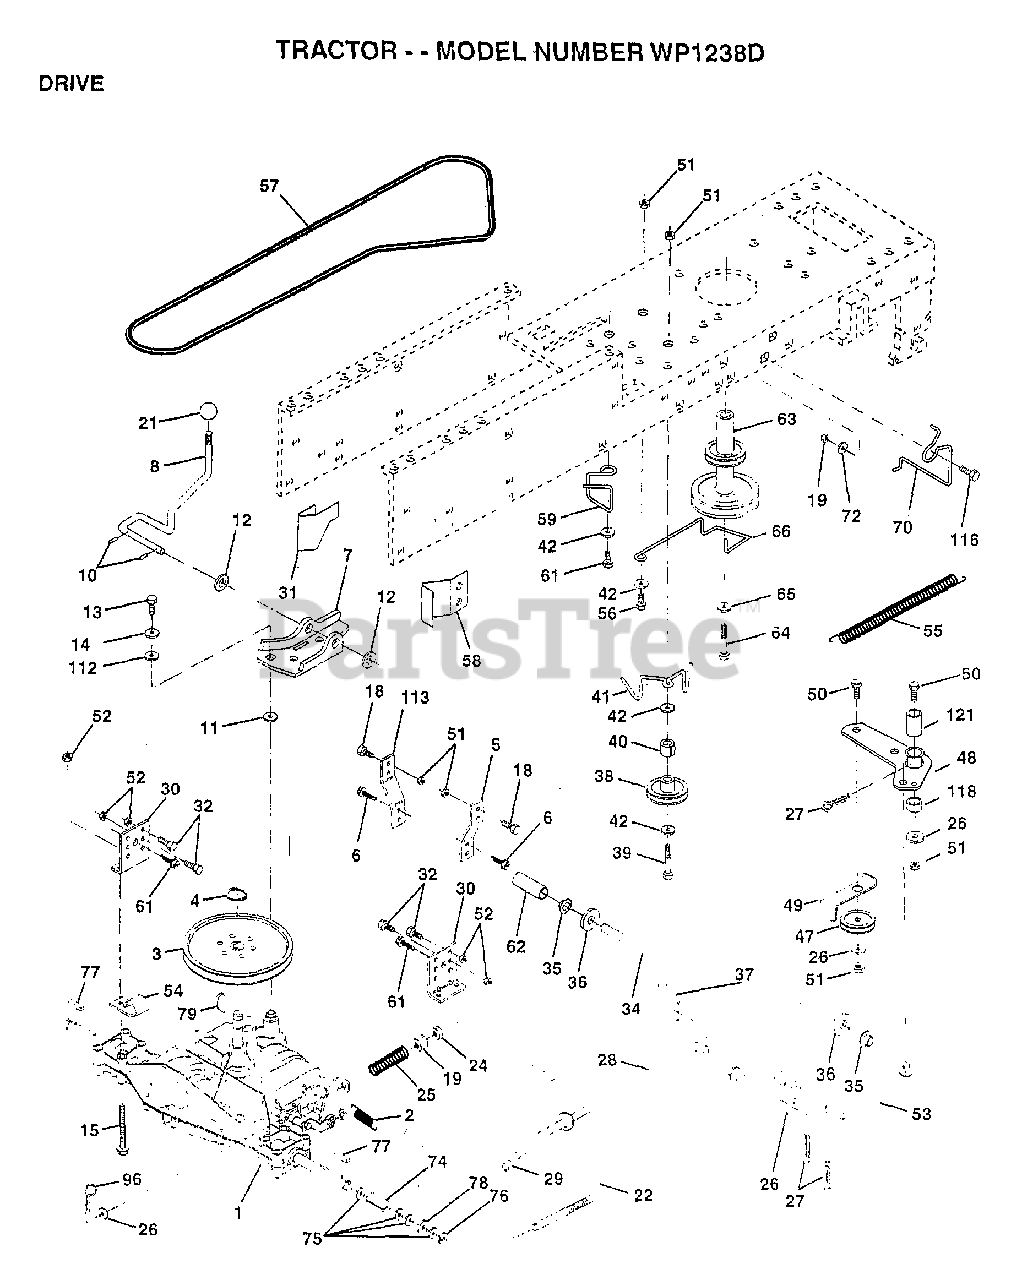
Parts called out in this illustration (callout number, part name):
1	TRANSAXLE, PEERLESS
2	SPRING.BRAKE.RETU
3	PULLEY TRANS
5	STRAP TORQUE
6	SCREW
8	SHIFT ROD
10	PIN COTTER 1/8
11	WASH-SHFT PLT LT
12	WASHER
13	BOLT.1/4-28.W/PAT
14	LOCKWASHER
15	BOLT.HX.FLG.5/16
18	BOLT
19	NUT
21	KNOB T (1/2-HOLE)
22	BRAKE ROD
24	NUT
25	SPRING ROD LT
26	WASHER
27	COTTER PIN
28	ROD.BRAKE.PARK.LT
29	PLUNGER CAP T
30	TRANSAXLE MTG BKT
31	"KEEPER,BELT LH T"
32	BOLT
34	SHAFT ASM-PEDAL F
35	NYLON BEARING
36	WASHER LT
38	PULLEY.IDLER.FLAT
39	BOLT
40	SPACER T
42	WASHER
48	BELLCRANK ASM
49	RETAIN BELT
53	"LINK, CLUTCH T"
54	CLIP T
55	"SPRING, RETURN LT"
58	"KEEPER,BELT RH T"
59	KEEPER BELT CNTSP
61	SCREW
62	PEDAL COVER T
63	PULLEY.ENGINE
64	BOLT
65	LOCKWASHER
66	KEEPER-BELT
70	KEEPER BELT ENG
72	WASHER
74	SPACER AXLE
75	WASHER
76	E-RING LT
77	SQUARE KEY
78	WASHER
96	RETAINER M
112	WASHER LT
113	"STRAP,TORQUE"
116	BOLT RDHD 3/8-16
118	SPACER-BELLCRANK
121	NYLINER-CLUTCHING
